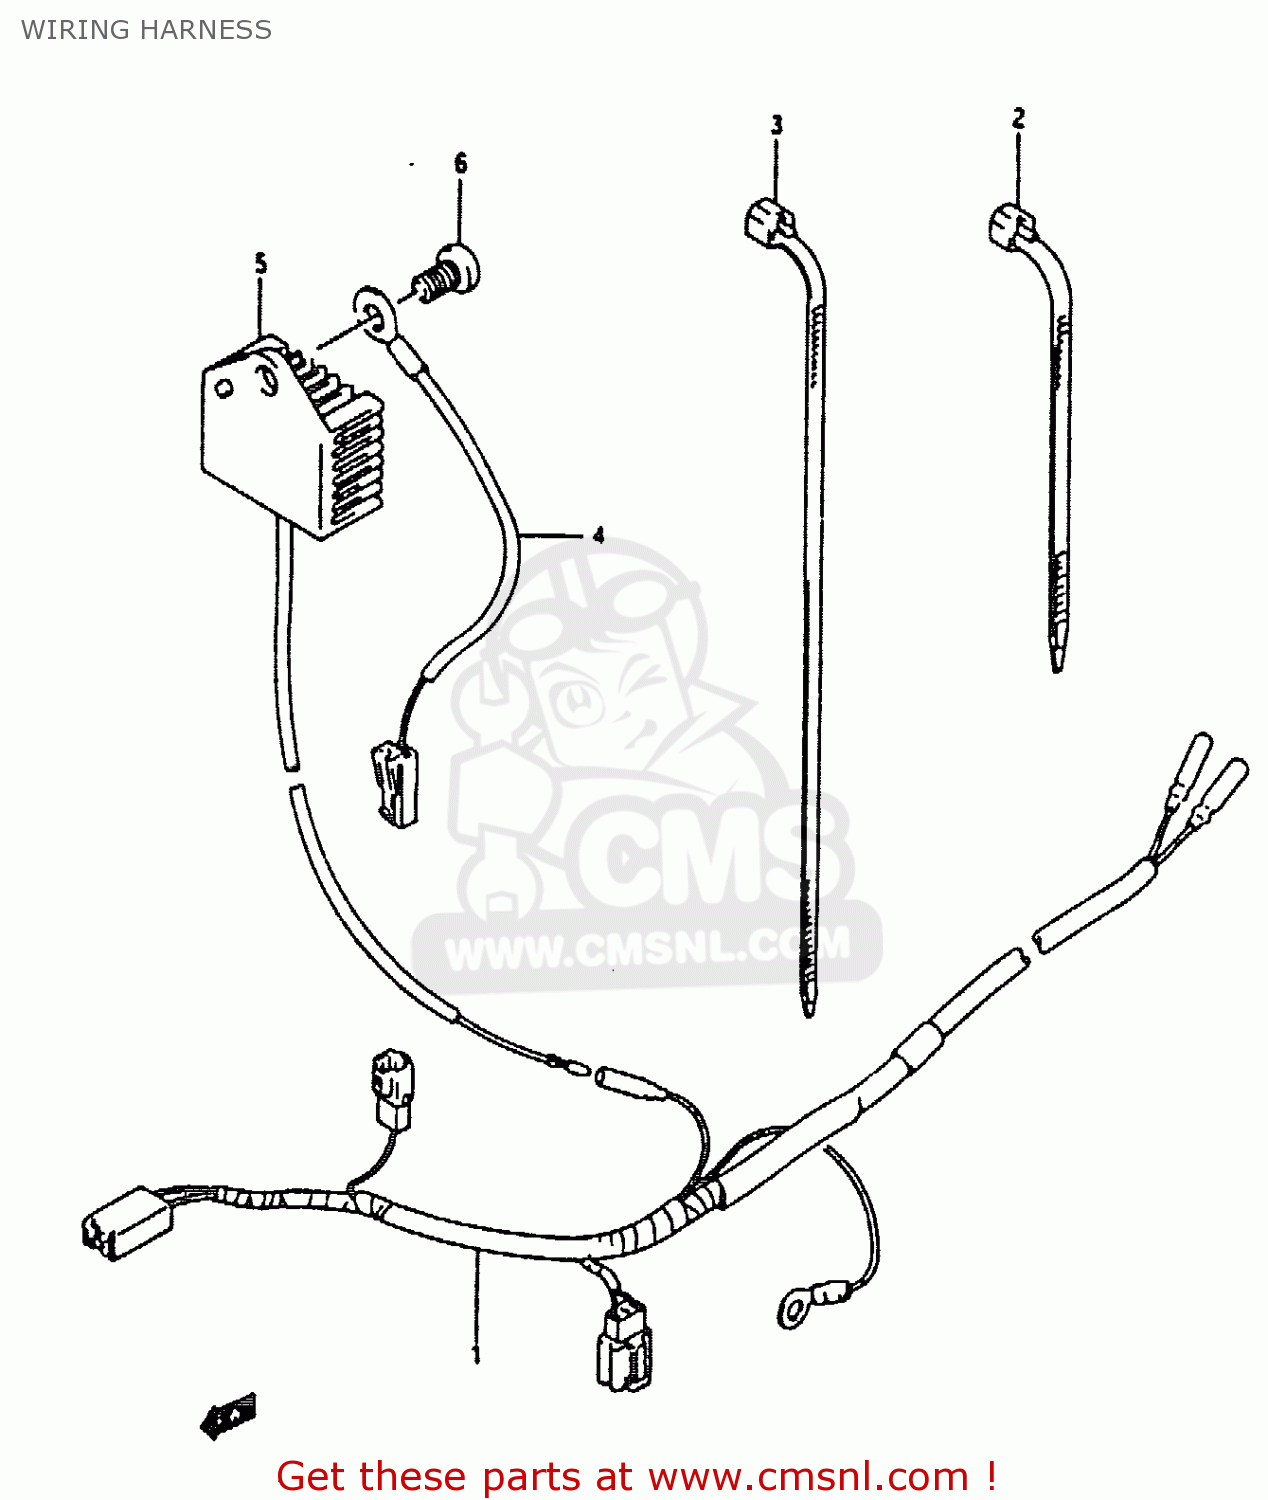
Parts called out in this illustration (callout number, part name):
1	HARNESS,WIRING
2	CLAMP(L:95)
3	CLAMP(L:235)
4	WIRE,REGULATOR EARTH LEAD
5	REGULATOR ASSY
6	SCREW
